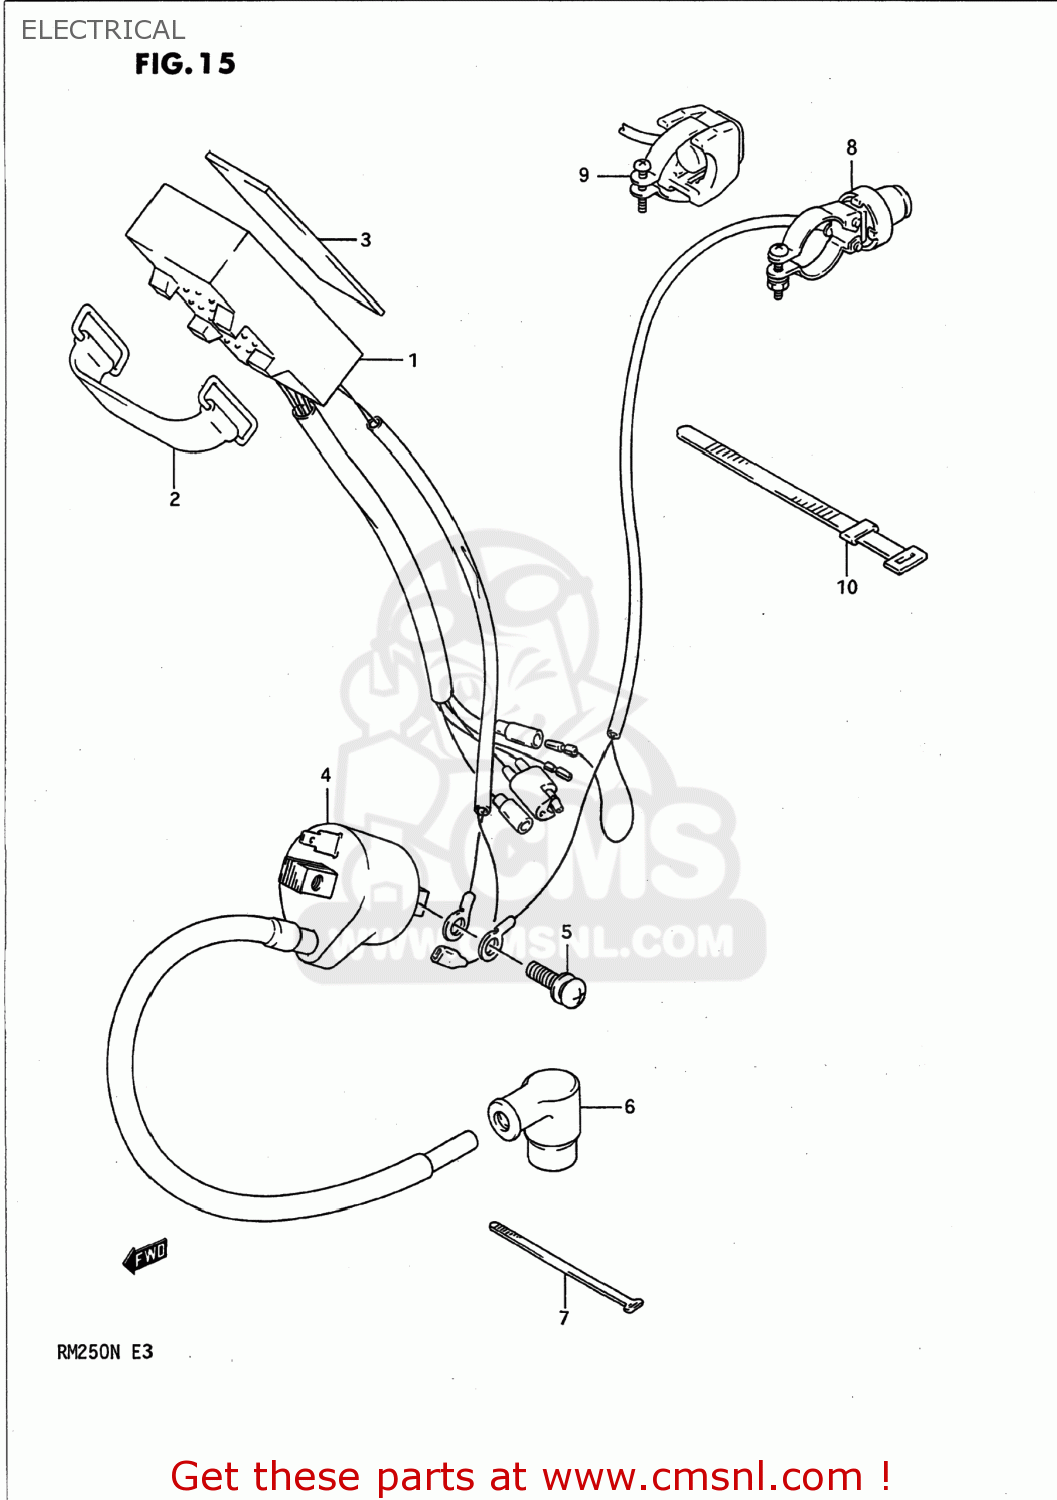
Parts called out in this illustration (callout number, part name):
1	CDI UNIT
2	BAND
3	PROTECTOR(170X95X3.0)
4	COIL ASSEMBLY,IGNITION
5	SCREW
6	CAP,SPARK PLUG
7	CLAMP
8	SWITCH ASSEMBLY
9	SWITCH ASSEMBLY
10	CLAMP(L:120)
